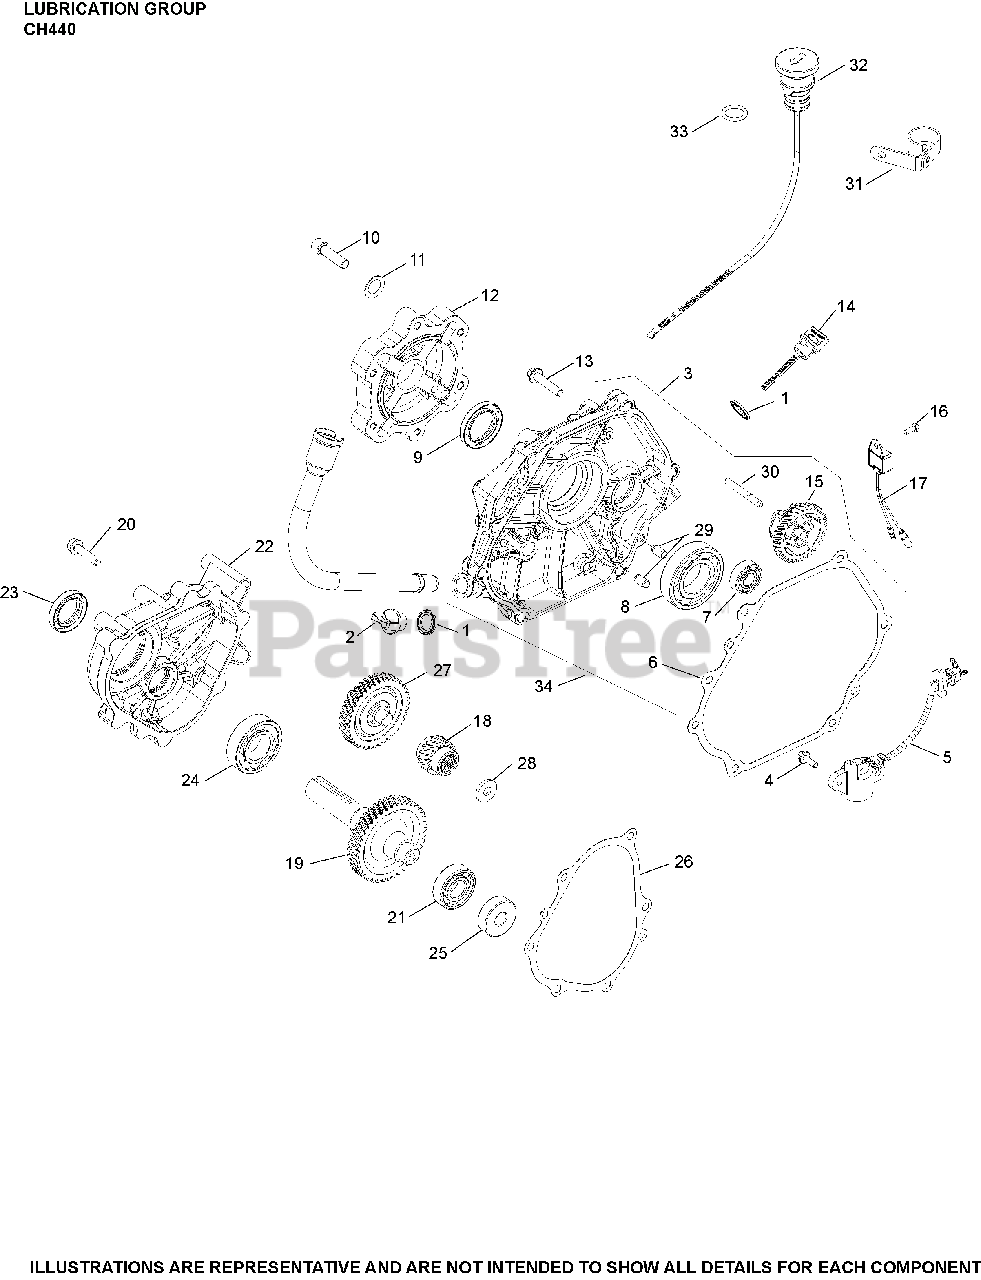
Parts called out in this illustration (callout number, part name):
1	SEAL, OIL
3	KIT, CLOSURE PLATE ASSEMBLY
4	SCREW, M6 X18
5	SWITCH, OIL SENSOR ASSEMBLY
6	GASKET, CLOSURE PLATE
7	BEARING, BALANCE SHAFT
8	BEARING , CRANKSHAFT
9	SEAL, CRANKSHAFT
13	SCREW, CLOSURE PLATE (CKY)
14	DIPSTICK ASSEMBLY
15	GOVERNOR ASSEMBLY
16	SCREW, HEX/PHILLIPS M5
17	CONTROL, OIL ALERT UNIT
30	SHAFT, GOVERNOR GEAR
